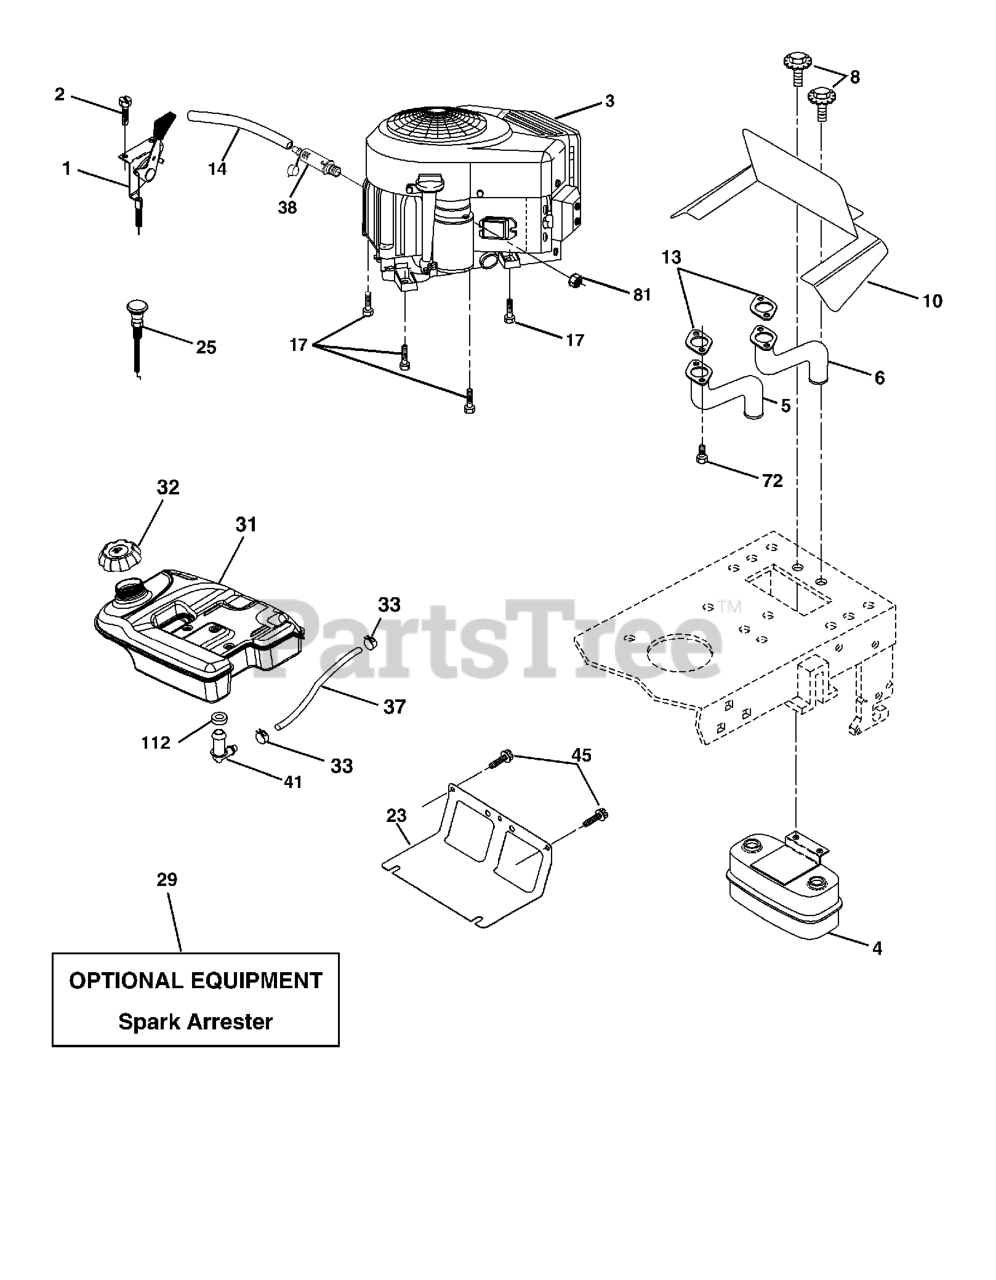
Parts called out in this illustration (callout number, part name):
1	CONTROL, THROTTLE
2	SCREW
4	MUFFLER.TWIN.CYL.LOW.TONE
5	RP.EXHAUST.TUBE.LH.BS/TWIN
6	EXHAUST.TUBE.RH.BS/TWIN
8	BOLT.5/16-18UNCX3/4 W/SEMS.BLK
10	SHIELD.BROWNING.B&S
13	GASKET.MUFFLER
14	TUBE, DRAIN OIL ASM.
17	SCREW 3/8-16 X 1-1/2
23	SHIELD.BROWNING.DBR.GUARD
25	CONTROL, CHOKE
26	Nut Keps 3/8 - 24 UNF
29	SPARK ARREST
31	4.0 REAR FUEL TANK
32	TANK CAP
33	HOSE CLAMP
37	REPL BY 532 00 85-43
38	PLUG DRAIN OIL EASY
41	STEM FUEL TANK
45	SCREW, 3/8-16X3/4
72	SCREW.SOCKET.HEAD.5/16-18
81	NUT
112	BUSHING OUTLET T
